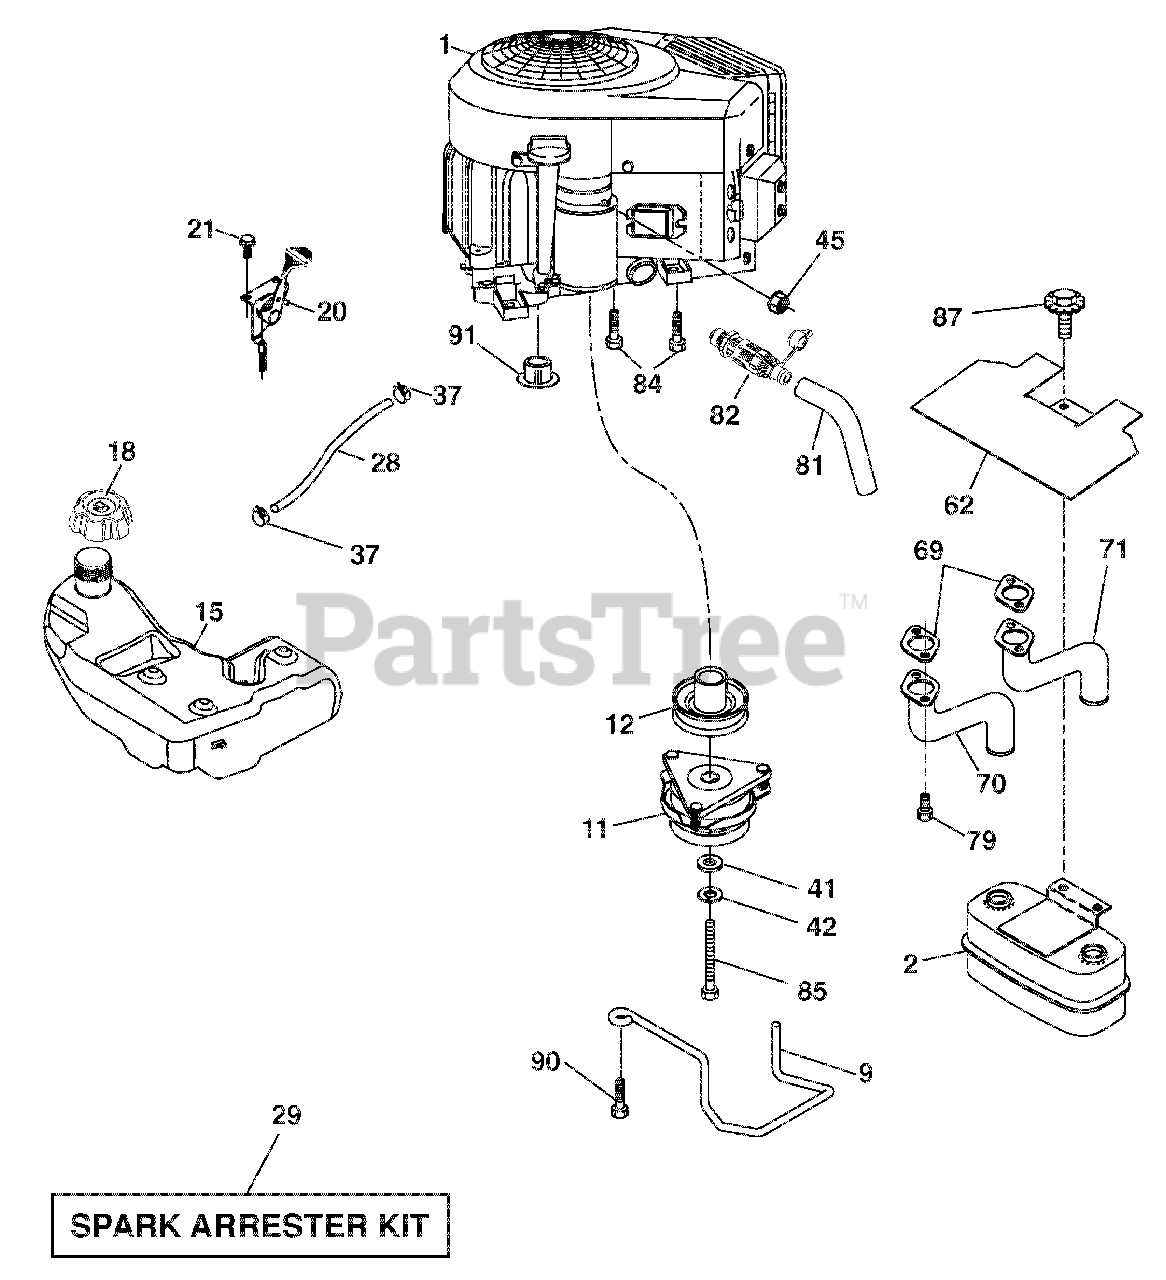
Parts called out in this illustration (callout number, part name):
1	ENGINE B&S MODEL NO. 44P777-4446-G5 (445979) (ORDER PARTS FROM ENGINE MANUFACTURER.)
2	MUFFLER ASM.TWIN.LO-TONE
9	KEEPER.BELT.ENGINE.4.25"NSTG
11	CLUTCH ELECTRIC
12	PULLEY.ENGINE
15	TANK.FUEL
18	CAP FUEL
20	CONTROL THROTTLE/CHOKE
28	LINE.FUEL.64"REAR.EMIS.CA.LP
29	KIT.SPARK ARRESTOR(392390 B&S)
37	CLAMP.HOSE.BLK.
41	WASHER.1-1/2 ODX15/32 IDX.250
42	WASHER.LOCK.HVY HLCL.SPR.7/16
45	Nut, Keps Hex 1/4-20 unc
62	SHIELD.HEAT.MUFFLER.
69	GASKET MUFFLER
70	EXHAUST TUBE LH
71	EXHAUST TUBE RH
79	SCREW SOCKET HEAD 5/16-18 X 1
81	TUBE.DRAIN.OIL.EASY
82	VALVE OIL DRAIN
84	Screw 3/8-16 x <
85	BOLT HEX 7/16-20 X 3.5 GR.5
87	BOLT.5/16-18 UNC X 1 W/SEMS.BL
90	SCREW.3/8-16X1.SMGML.TAP/R.BLK
91	BUSHING.1.375OD.HEYCO 2210
